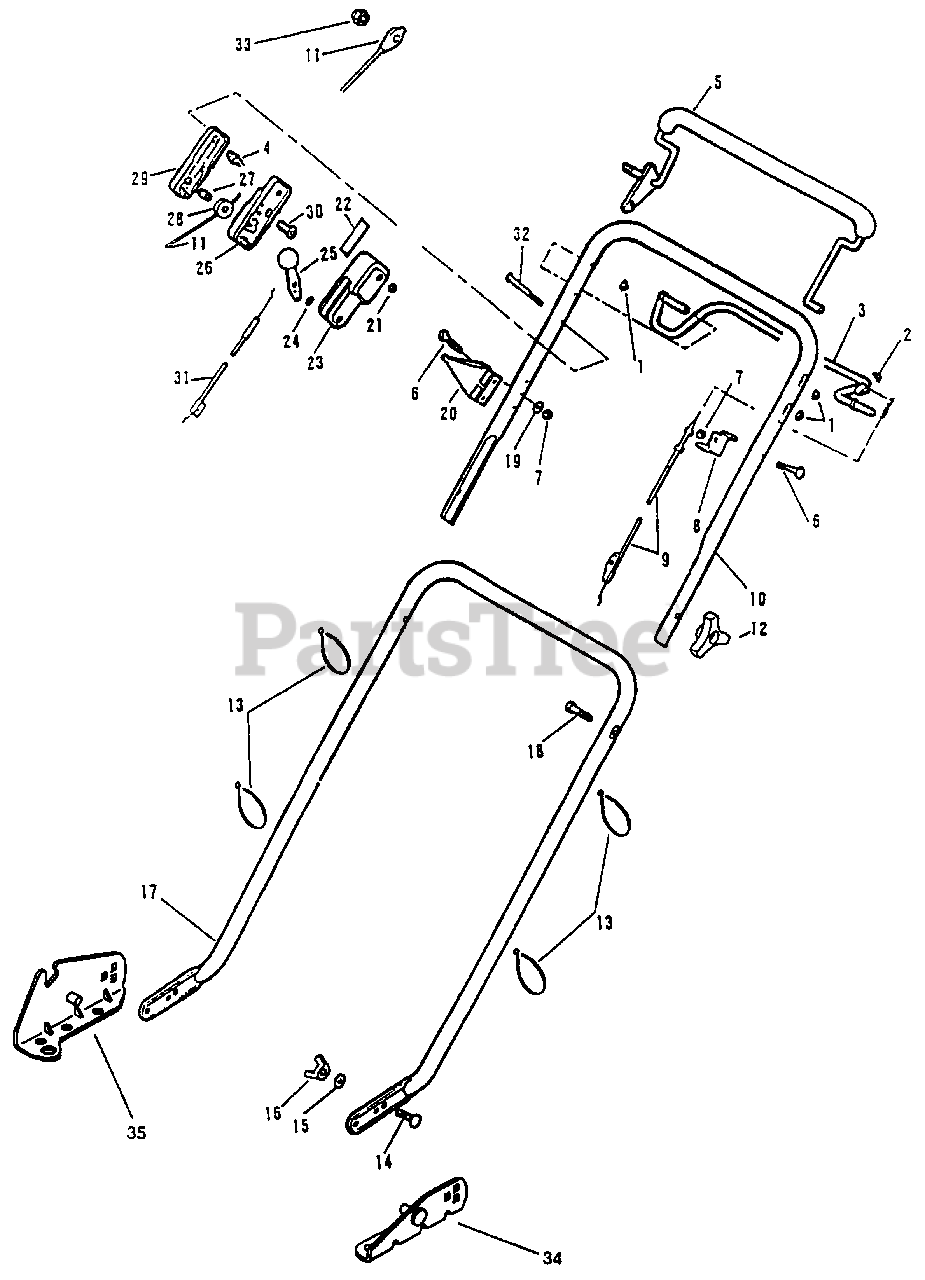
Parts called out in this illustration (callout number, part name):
1	Palnut (Self Propelled)
2	Palnut (Self Propelled)
3	Self Propel Bail (Self Propelled)
4	Column
5	Control Lever Assembly
6	Screw (Self Propelled)
7	Nut (Self Propelled)
8	Conduit Anchor (Self Propelled)
9	Control Cable (Self Propelled)
10	Handle-Top (Self Propelled)
11	Engine Control Cable
12	Handle Knob
13	Tie Strap
14	Bolt-Handle To Handle Bracket
15	Washer
16	Wing Nut
17	Handle-Lower (Self Propelled)
18	Screw
19	Washer
20	Rope Guide Assembly
21	Nut
22	Decal-Throttle Control
23	Throttle Case-Inner
24	Washer
25	Lever & Knob Assembly
26	Throttle Case-Center
27	Pin
28	Pulley
29	Control Case-Outer
30	Screw
31	Throttle Cable
32	Screw
33	Acorn Nut
34	Handle Bracket-L.H. (Push)
35	Handle Bracket-R.H. (Push)
